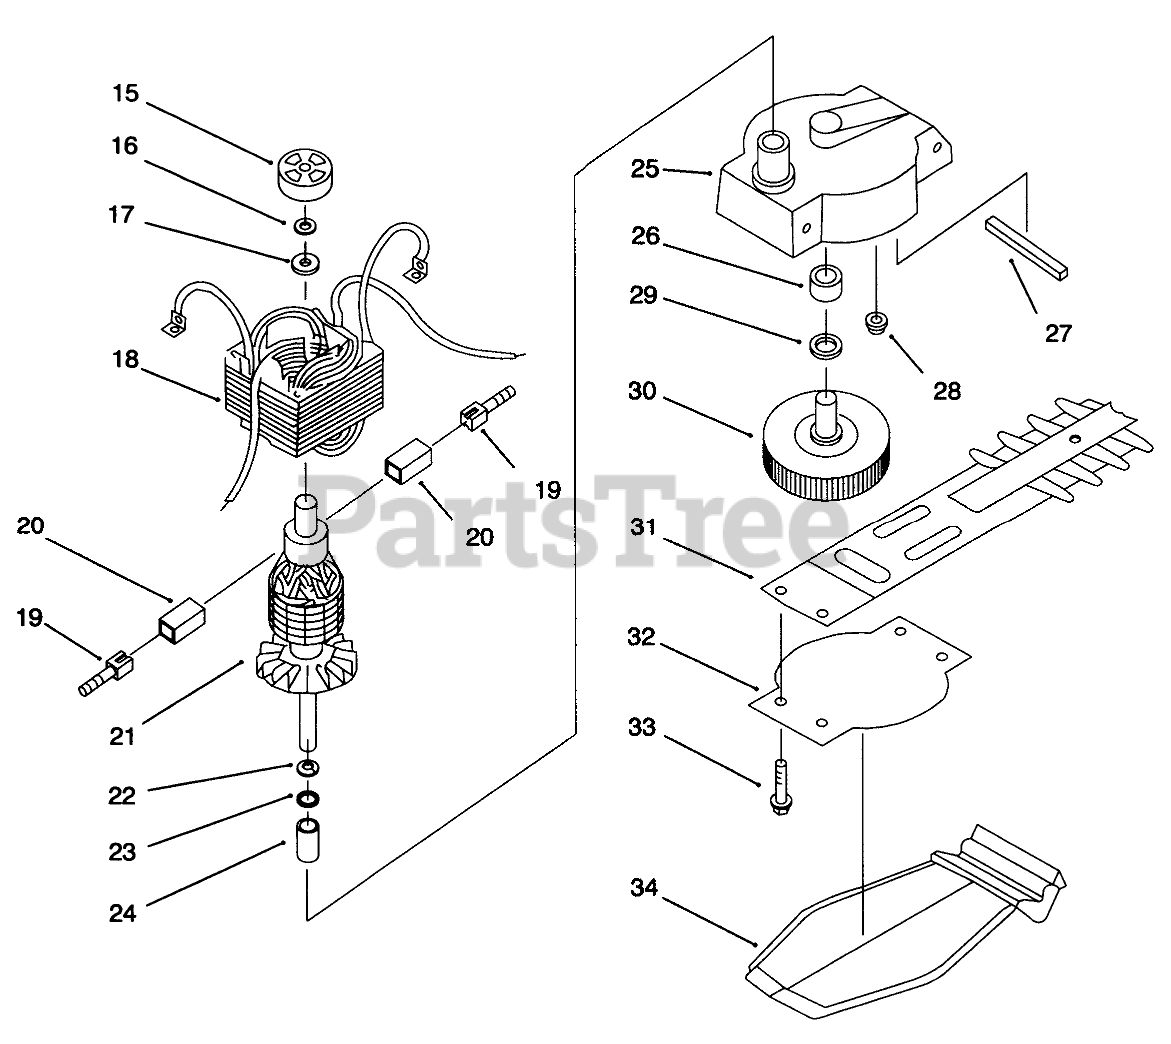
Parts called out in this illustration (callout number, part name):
20	TUBE - BRUSH
21	ARMATURE
23	WASHER
30	ASSEMBLY - GEAR
33	SCREW
